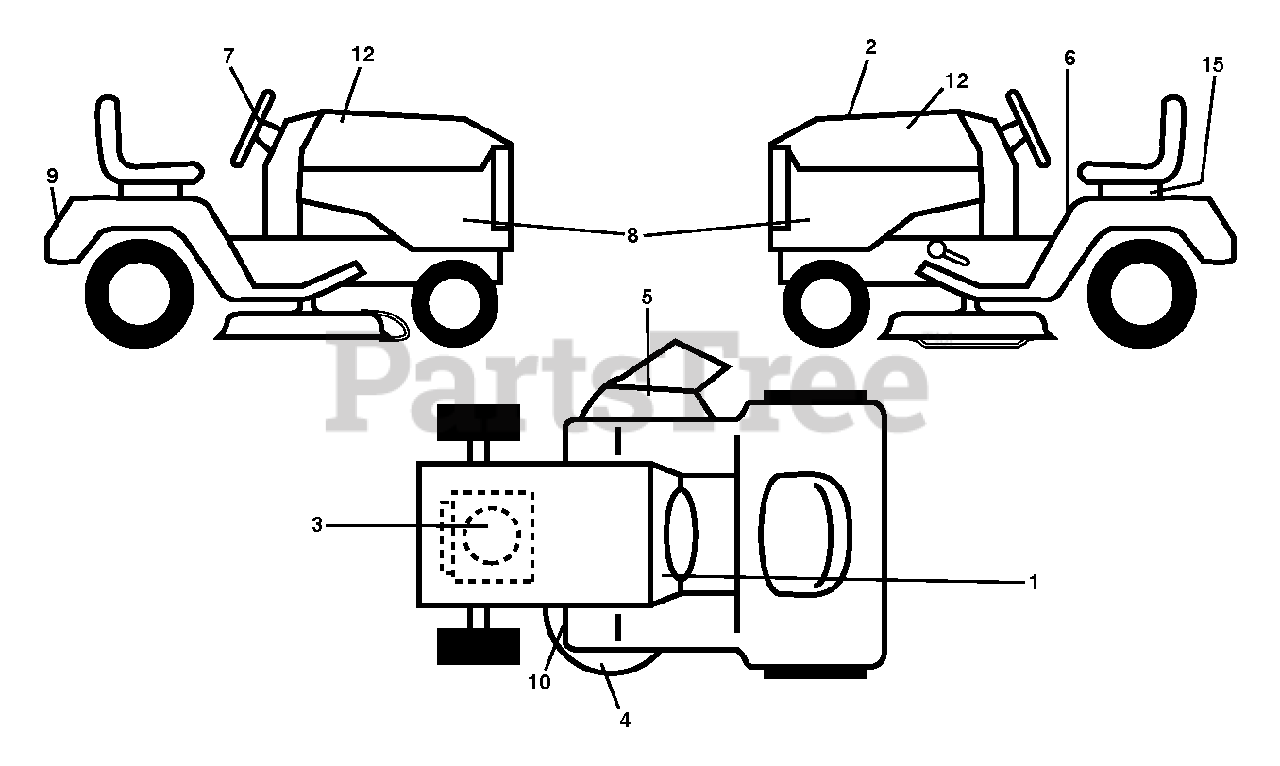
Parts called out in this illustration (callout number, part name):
1	DECAL.DASH.SNOWFLAKE.BLACK.SM
2	DECAL DECAL.RPL.BSM33.INTK.LT.
3	Decal, Engine BSM33 INTEK 19HP RS
4	DECAL.PPRO.10YRDECKWAR.POP
5	DECAL, DECK DEFLECTOR, WARNING
6	DECAL.FENDER.WARNING.ENGLISH
7	Decal, Steering Wheel STDXXSQ PPRO 2015
8	Tractor Side Panel Decal
9	DECAL.REARFNDR.POULAN PRO.2015
10	DECAL.V-BELT.SCH.42/46"MEC/ELE
12	DECAL.POULAN PRO.2015
15	DECAL BTRY SYMBOLS
